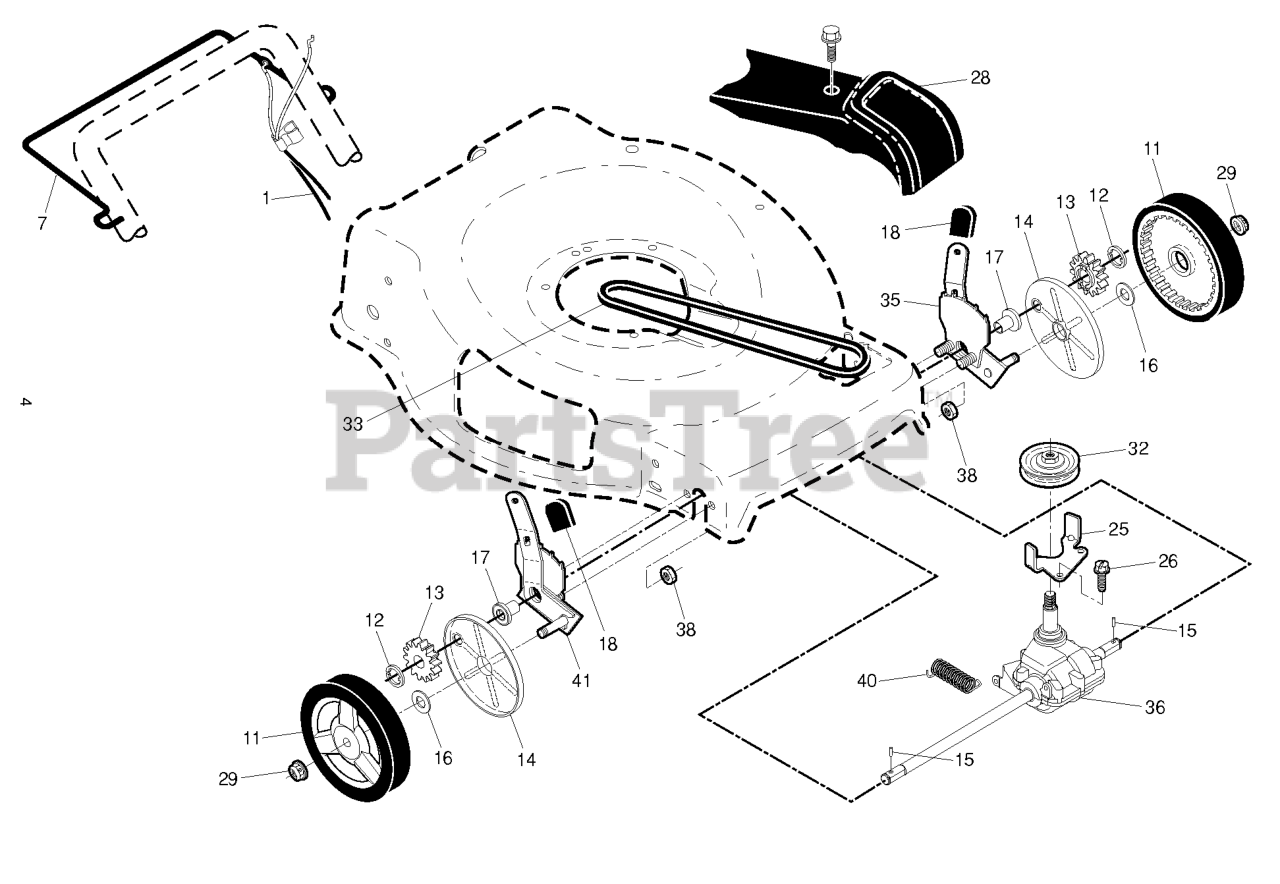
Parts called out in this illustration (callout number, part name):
1	CABLE.DRIVE.VS/SS.22+FGD.MCCUL
7	BAIL.CURVED.UNDER.BAIL.BLACK
11	WHEEL.8X1.75.H3SPK.RAD3.GY.BU3
12	E-RING 7/16 RE
13	PINION.14.TEETH.FGD
14	COVER.DUST.WHEEL.INNER.WALK
15	PAWL, DRIVE
16	WASHER FLUT
18	SELECTOR KNOB
25	BRACKET.BELT.GUIDE.22+FGD.BZP
28	COVER.DR.ASM.421097.HUSQ.CE
29	NUT.HEX.FLANGE.3/8-16.LO(3 2)
32	RP PULLEY.DRIVE.EZ/VAR.SCREWON
33	BELT.DRIVE.FGD.
35	RP ADJ.ASM.9.22+/LF/RR.21/RF
36	RP.TRANSMISSION.22+.FWGD.SS
38	NUT.HEX.FLANGE.1/4
41	RP_ADJUSTER.ASM.9.22+/RF/LR.21
